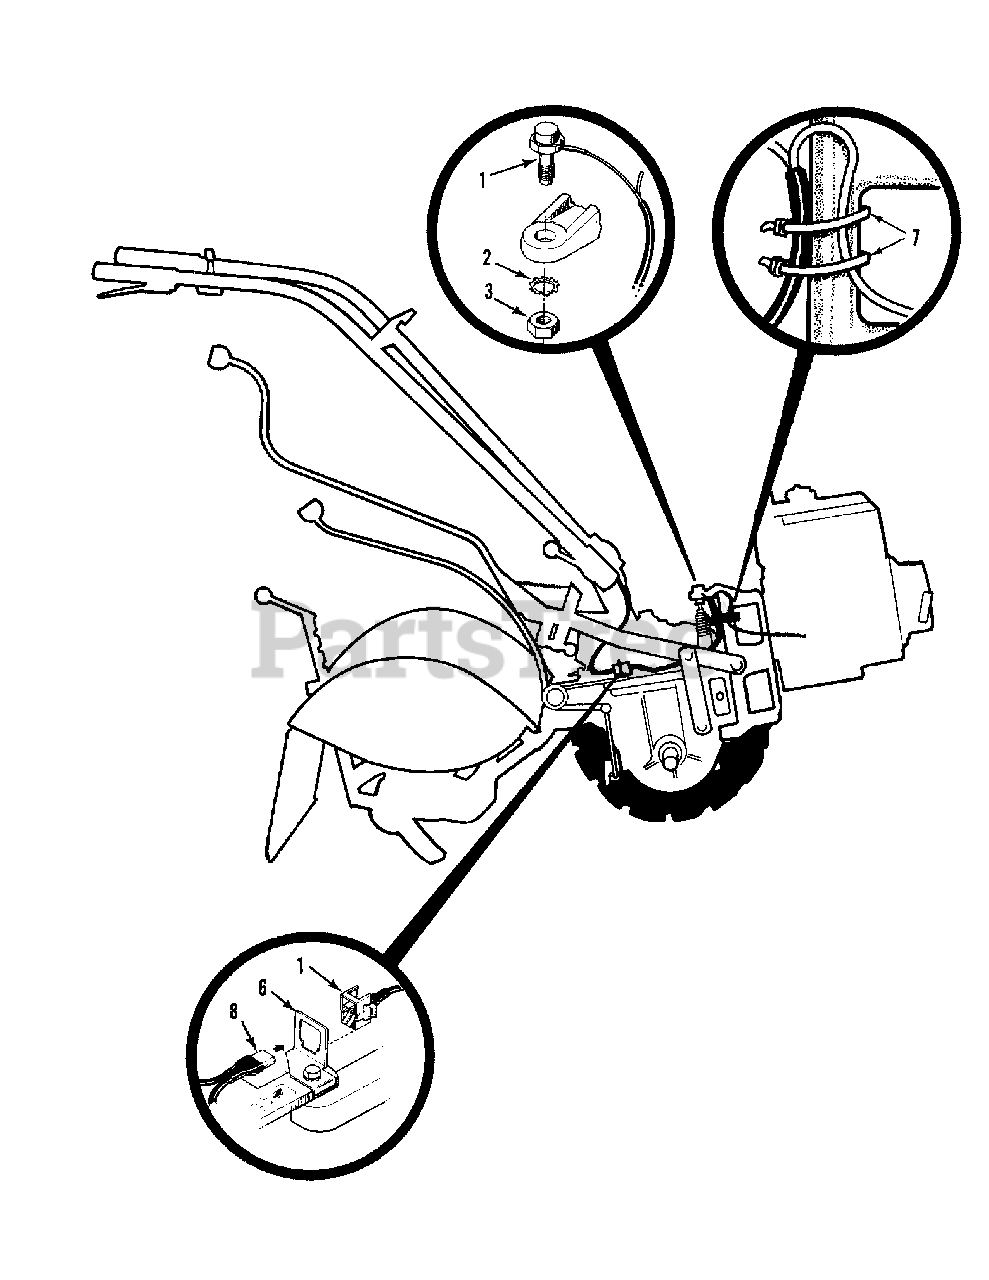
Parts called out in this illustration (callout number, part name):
1	Engine Wire Harness Assy interlock system. Parts not available separately.
2	Lockwasher - external tooth 7/16
3	Nut-hex, 7/16"-20
6	Clip-for plug connector
7	Tie-plastic
8	Handlebar Wire Harness Assembly (see Handlebar Assembly, Ref. #20)
